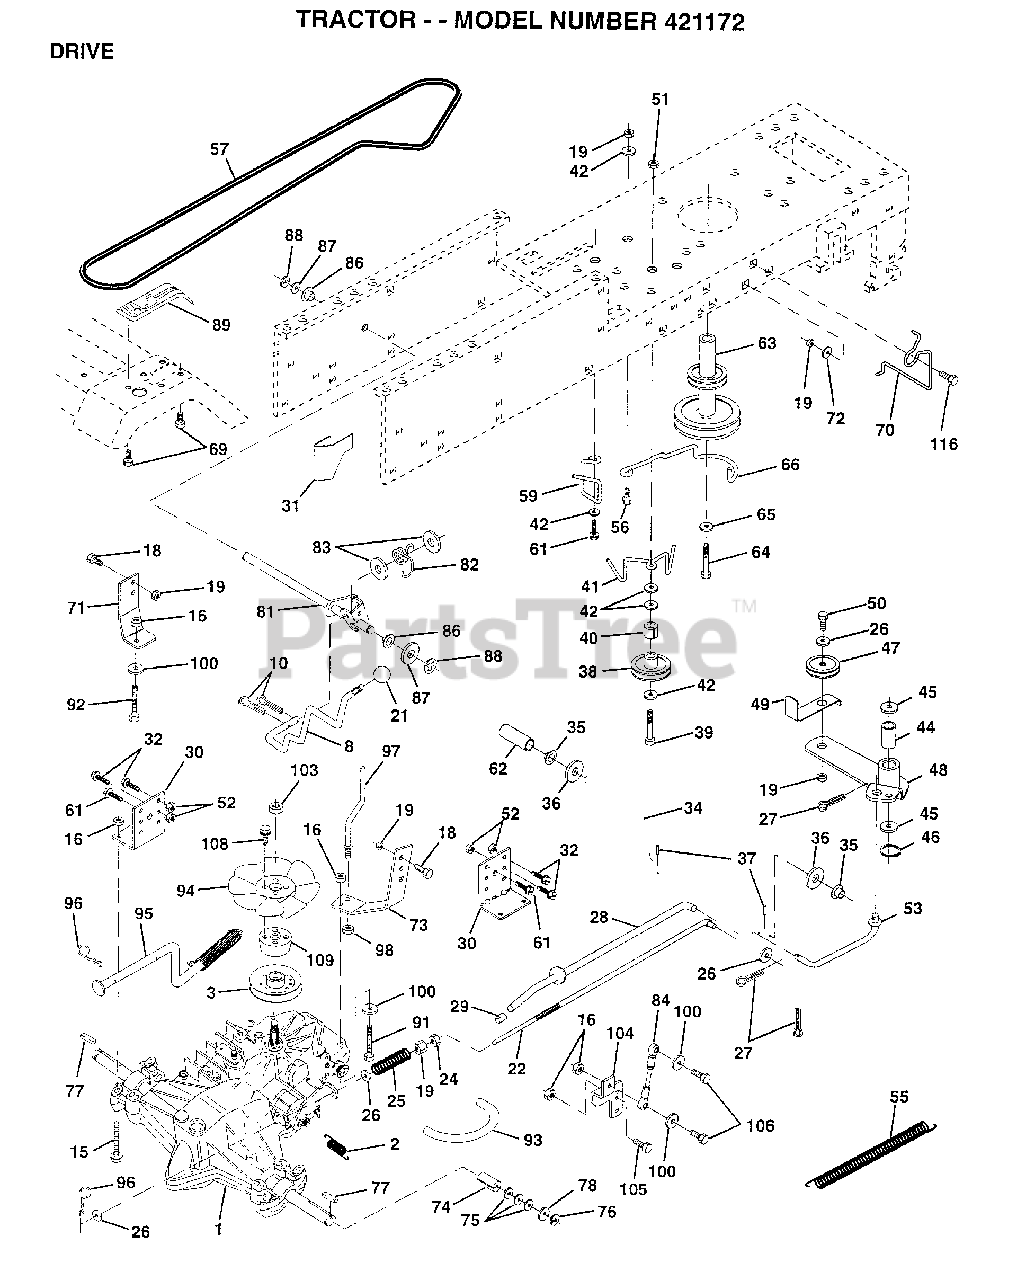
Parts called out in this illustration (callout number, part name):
1	TRANSAXLE HYD 0319-0500
2	SPRING RET BRAKE
3	PULLEY.4.20.HYDRO
8	ROD SHIFT FEND LT
10	PIN COTTER 1/8
15	BOLT.HX.FLG.5/16
16	NUT
18	BOLT
19	NUT
21	KNOB DLX BLK/BLK
22	ROD.BRAKE.HYDRO.
24	NUT
25	SPRING ROD LT
26	WASHER
27	COTTER PIN
28	ROD.BRAKE.PARK.LT
29	PLUNGER CAP T
30	TRANSAXLE MTG BKT
31	"KEEPER,BELT LH T"
32	BOLT
34	SHAFT FOOT PEDAL
35	NYLON BEARING
36	WASHER LT
38	PULLEY.IDLER.FLAT
39	BOLT
40	SPACER T
41	KEEPER BELT
42	WASHER
44	"LY, BEARING"
45	WASHER LT
46	KLIP RING
48	ARM IDLER
49	RETAIN BELT
53	"LINK, CLUTCH T"
55	"SPRING, RETURN LT"
57	BELT-V.HYDR.84.61
59	KEEPER BELT CNTSP
61	SCREW
62	PEDAL COVER T
63	PULLEY.ENGINE
64	BOLT
65	LOCKWASHER
69	SCREW HEXWSH H-L
70	KEEPER BELT ENG
71	STRAP.TORQ.LH.HYD
72	WASHER
73	STRAP.TORQ.RH.HYD
74	SPACER SPLIT
75	WASHER
76	E-RING LT
77	SQUARE KEY
78	WASHER
81	SHAFT.CROSS.HYD
82	"SPRING,TORSION"
83	WASHER
84	ROD.TIE.BALL.HYD.
86	BUSHING
87	WASHER D
88	KLIP RING
92	HEX BOLT
93	"LINE FUEL HYD 4"""
94	"FAN 7"" HYDRO"
96	RETAINER M
97	KEEPER.BELT.RH.HY
98	NUT
100	WASHER M
104	ARM.CONTROL.PUMP
105	SCREW CAP 5/16-18
106	BOLT
108	SCREW.HXHD.10-20
109	ADAPTOR.FAN.HYDRO
116	BOLT RDHD 3/8-16
